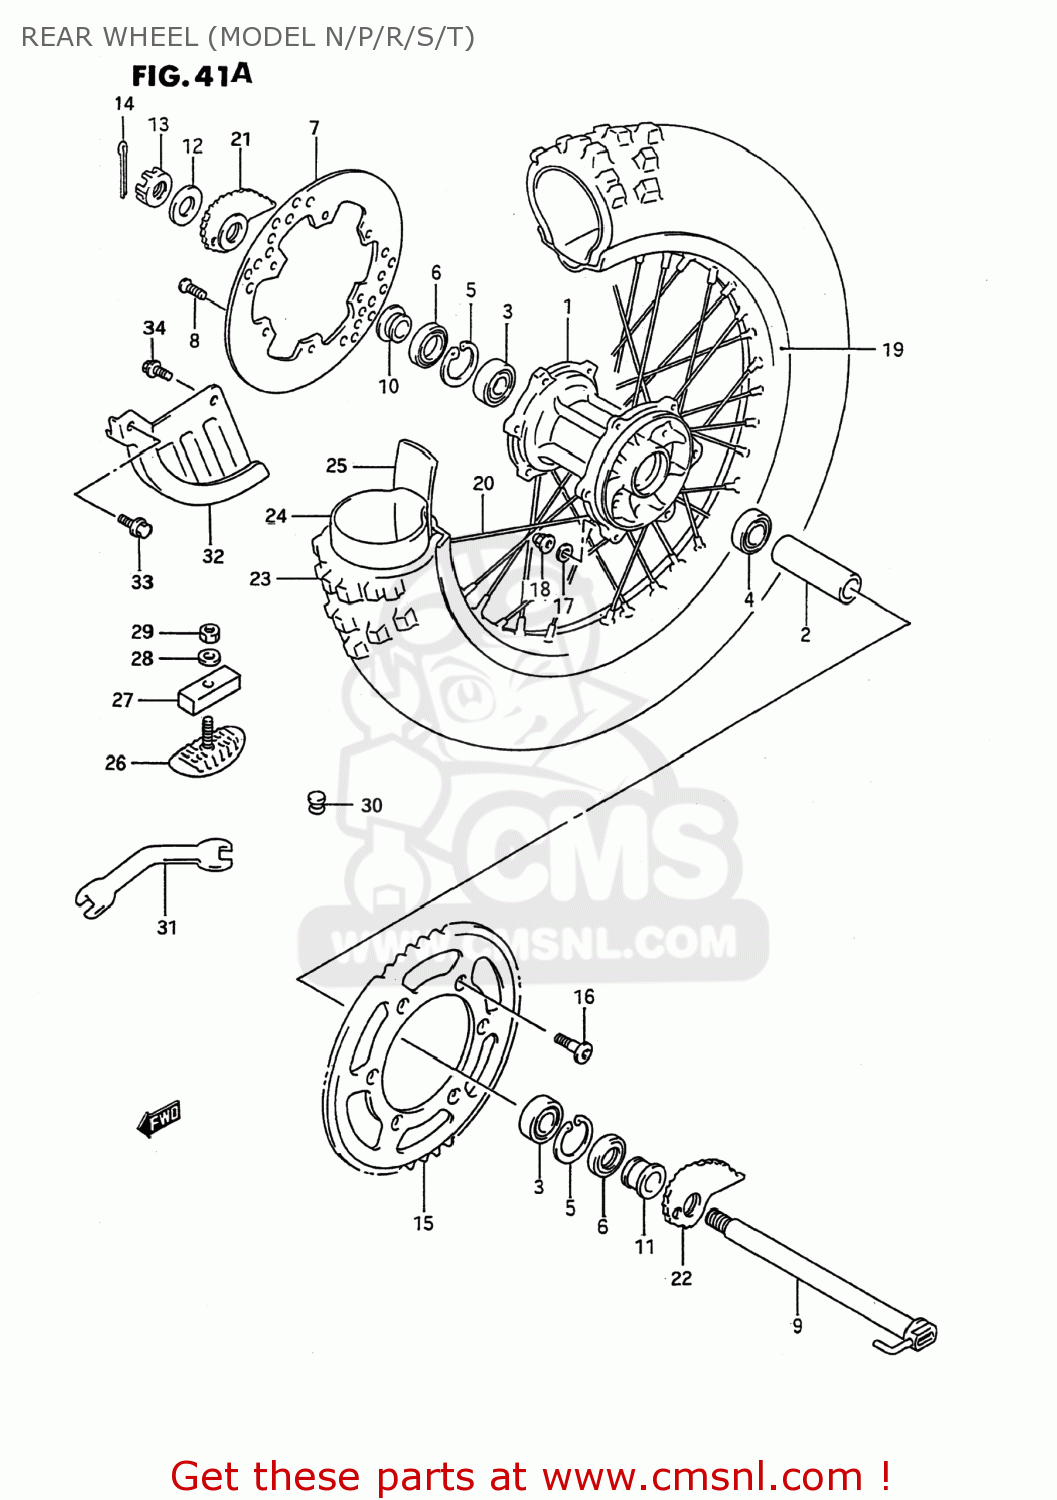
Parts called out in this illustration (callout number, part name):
1	HUB,RR
2	SPACER,RR HUB BEARING
3	BEARING WHEEL REAR(20X47X14)
4	BALL BEARING
5	CIRCLIP,14MM
6	SEAL,OIL(26X47X5)
7	DISC,RR BRAKE
8	SCREW
9	AXLE,RR
10	SPACER,RR AXLE,R
11	SPACER,RR AXLE,L
12	WASHER(19X32X3.2)
13	NUT
14	PIN,COTTER
15	SPROCKET,REAR
16	SCREW(8X33.5)
17	WASHER
18	NUT
19	RIM,REAR WHEEL (2.15X18)(A
20	SPOKE ASSY,RR WHEEL
21	ADJUSTER,CHAIN,R
22	ADJUSTER,CHAIN,L
23	TIRE,REAR 110/100-18
24	TUBE ASSEMBLY,WHEEL,INNER
25	PROTECTOR,INNER TUBE
26	STOPPER,BEAD
27	CUSHION,BEAD STOPPER
28	WASHER
29	NUT
30	CAP(OD:12)
31	SPANNER,OPEN
32	COVER,REAR DISC
33	BOLT 6X20
34	BOLT
